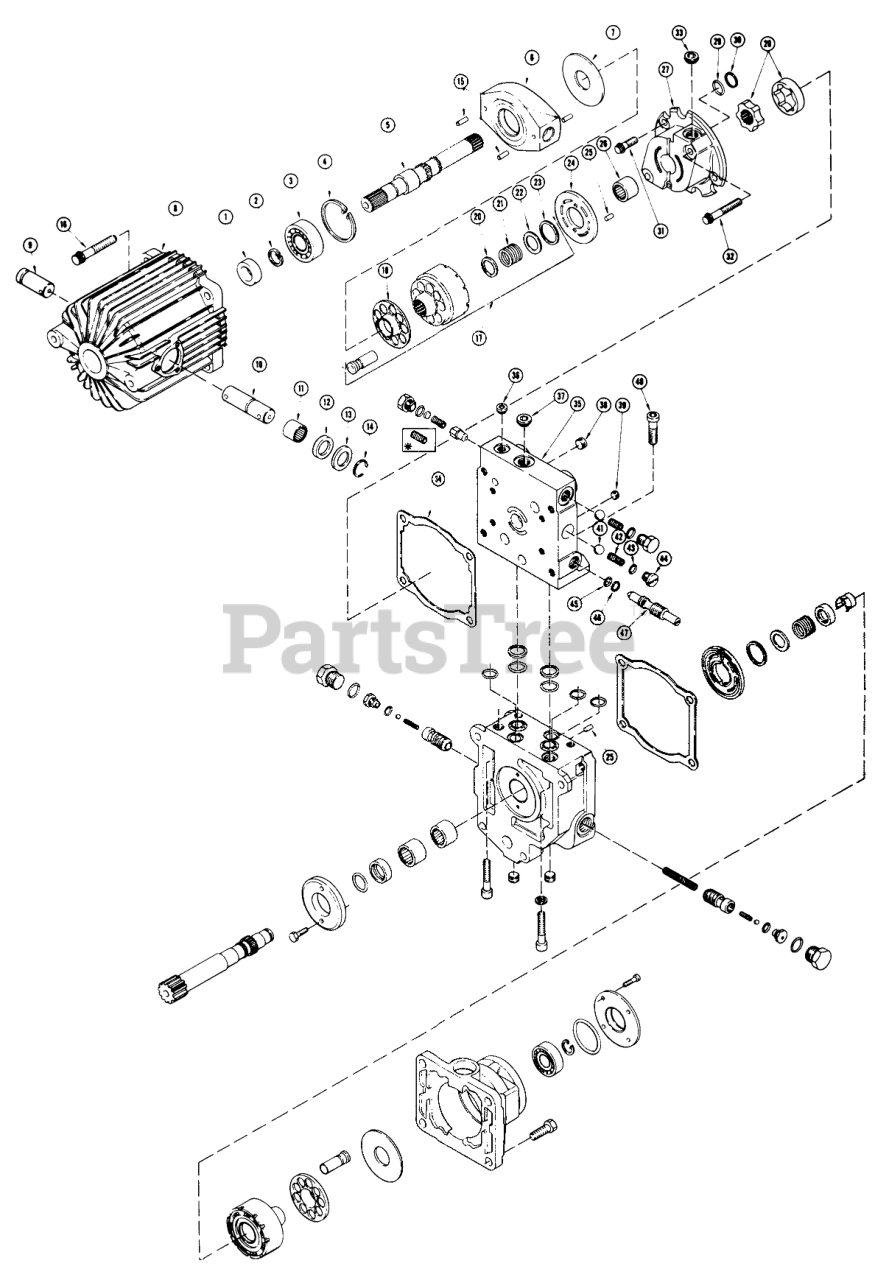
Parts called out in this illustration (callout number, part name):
1	SEAL
2	Snap Ring
3	Ball Bearing
5	Pump Shaft
6	Variable Swash Plate
7	Thrust Plate
8	Pump Housing
9	Stub Trunnion Shaft
10	Trunnion Shaft
11	Needle Bearing
12	SEAL
13	WASHER-LAMBERT
14	RING-LAMBERT
15	Spirol Pin
16	Cap Screw
17	Cylinder Block Kit Inc 18-22
18	RETAINER-SUN 3100194
20	Spacer
21	Spring
22	Front Washer
23	RING-SUN9006250-0112
24	PLATE-VALVE
25	Locating Pin
26	Needle Bearing
27	Charge Pump Housing
28	Assy-Gerotor
29	O RING
30	RING BACKUP
31	Cap Screw Short
32	Cap Screw Long
33	Socket Head Plug
34	Gasket-Pump
35	End Cap-Pump
36	Socket Head Plug
37	Socket Head Plug
38	Pipe Plug
39	Pipe Plug
40	Cap Screw
41	Ball
42	Spring
43	O RING
44	PLUG
45	O-RING
46	Back Up Ring
47	VALVE
